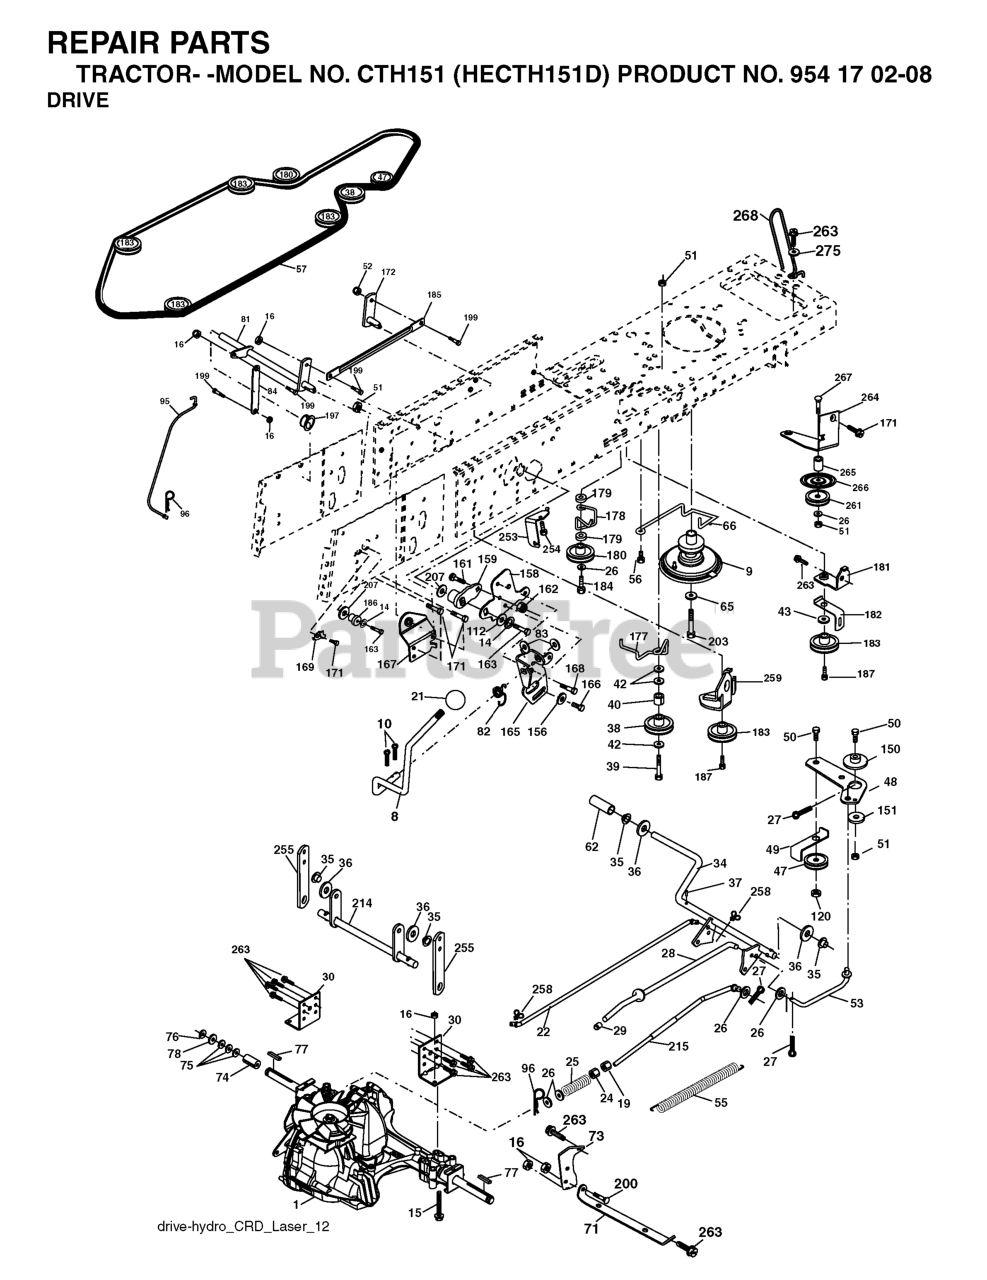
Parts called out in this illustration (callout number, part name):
8	ROD.SHIFT.FENDER.ADJ.LT.CRD
9	RP CLUTCH.NORAM.2002
10	PIN COTTER
14	LOCKWASHER
15	BOLT HEX 5/16-18 GR 5
16	NUT.71038.31-18.HEX.NYLOCK
19	NUT
21	KNOB.DUCKHEAD.1/2
22	ROD
24	NUT
25	SPRING BRAKE ROD
26	WASHER
27	COTTER PIN
28	ROD, PARKING BRAKE
29	PLUNGER CAP
30	BRKT, TRNSXLE MNT 20"
34	SHAFT, FOOT PEDAL
35	BEARING.NYLON
36	WASHER LT
37	DRIVE PIN
38	PULLEY.FLAT
42	WASHER
43	WASHER T
47	IDLER PULLEY
48	BELLCRANK, CLUTCH
49	RETAIN BELT
50	BOLT.3/8-16X1.50
52	LOCKNUT
53	LINK, CLUTCH LT
55	SPRING, RETURN LT
56	SCREW.3/8-16
57	V-BELT 113"
62	COVER, PEDAL (1 2)
65	LOCKWASHER
66	KEEPER BELT ENGINE
71	STRAP TORQUE RH HYDRO
73	STRAP TORQUE LH HYDRO
74	SPACER AXLE
77	SQUARE KEY
81	ASM.CROSS.SHAFT.REAR.CRD.0510
82	SHIFT SPRING
83	WASHER
84	LINK.PNT.TRANSAXLE.0510.CRD
95	LINK
96	RETAINER M
112	WASHER LT
120	NUT LOCK FLG 3/8-16 UNC
150	BUSHING.BELLCRANK.GRD.DR
151	WASHER 12/32X2X10GA
156	WASHER.SRRTD.5/16
158	BRACKET
159	RB HUB.SHIFT
161	BOLT
162	NUT.CROWNLOCK.1/4
163	BOLT
165	RP BRACKET
166	CAPSCREW.HXHD.FLG.5/16-18X.625
167	BRACKET.SUPT.SHIFT.CRD
168	BOLT.SHOULDER.5/16-18X
169	PLATE.FASTENING.CROSS.SHAFT
171	SCREW LT
172	LINK
180	PULLEY.FLAT.IDLER
181	BRACKET
182	BELT GUIDE
184	SCREW.HXWSH.3/8
185	LINK
186	HUB.TAPERED.ROUND.CRD
187	BOLT.5/16-18X1.25
197	NYLINER SNAP 5/8" ID
199	BOLT SHOULDER 5/16-18 UNC
200	BOLT
203	BOLT.HEX.7/16-20 X 5
207	WASHER NYL
214	LEVER
215	ROD
254	SCREW 3/8-16X1
255	SHAFT
258	CLIP RETAINER
259	BRACKET
261	FLAT IDLER PULLEY
263	SCREW, 3/8-16X3/4
265	SPACER IDLER
266	PROTECTOR
268	GUARD MUFFLER
275	WASHER
